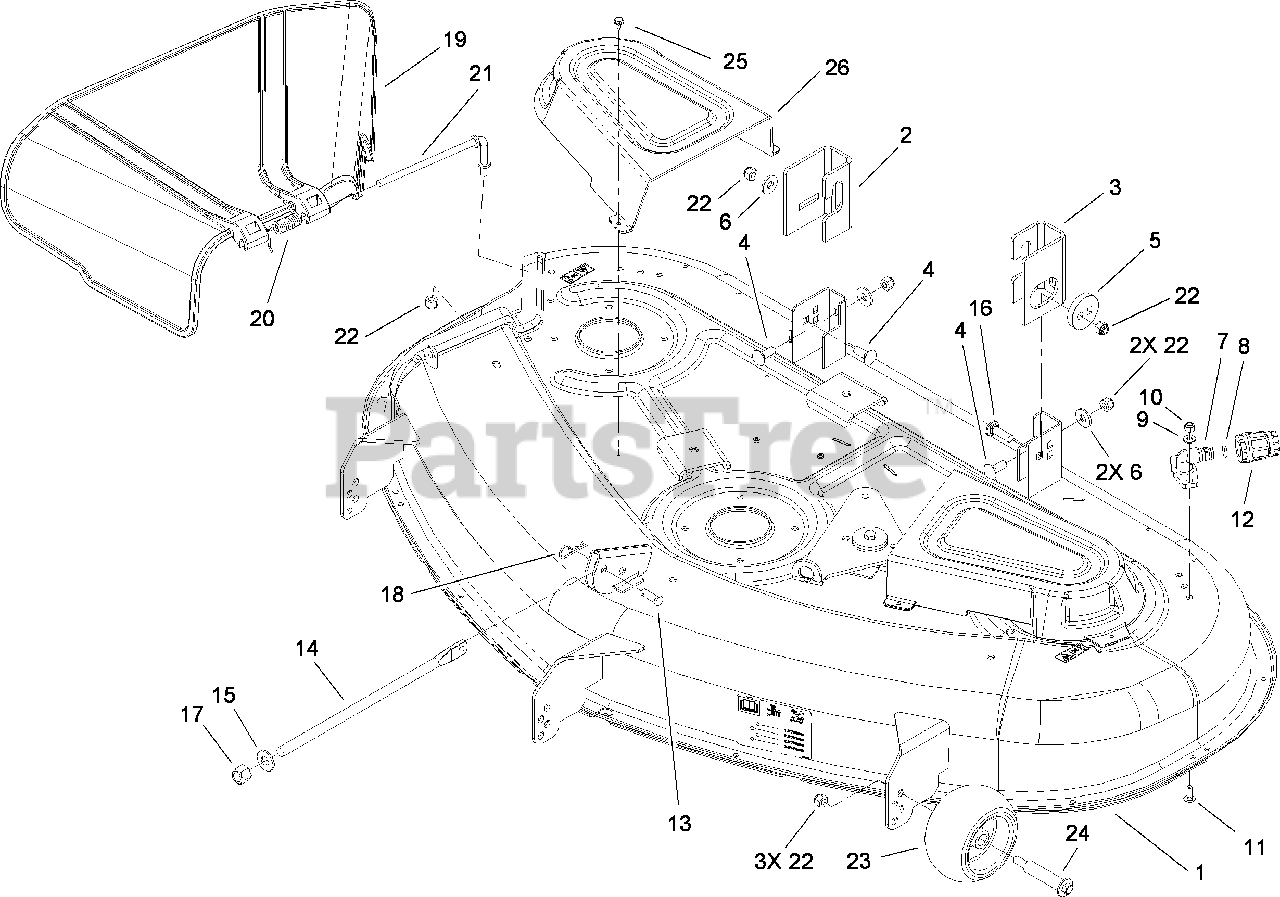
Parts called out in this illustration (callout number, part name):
1	50 INCH DECK ASM
2	BRACKET-HANGER, RIGHT REAR
3	BRACKET-HANGER, LEFT REAR
4	SCREW-CARR
5	ECCENTRIC
6	WASHER-HARDENED
7	FITTING-WASHOUT
8	O-RING, SEAL
9	WASHER-FLAT
10	NUT-LOCK, NI
11	SCREW-CARR
12	CONNECTOR-HOSE
13	PIN-CLEVIS
15	WASHER-THRUST
16	SCREW-CARR
17	NUT-LOCK, NI
18	PIN-HAIR
19	DEFLECTOR-50 INCH
20	SPRING-TORSION
21	ROD-PIVOT
22	NUT-LOCK, NI
23	ROLLER-SCALP, ANTI
24	BOLT-SHOULDER
26	COVER-BELT
